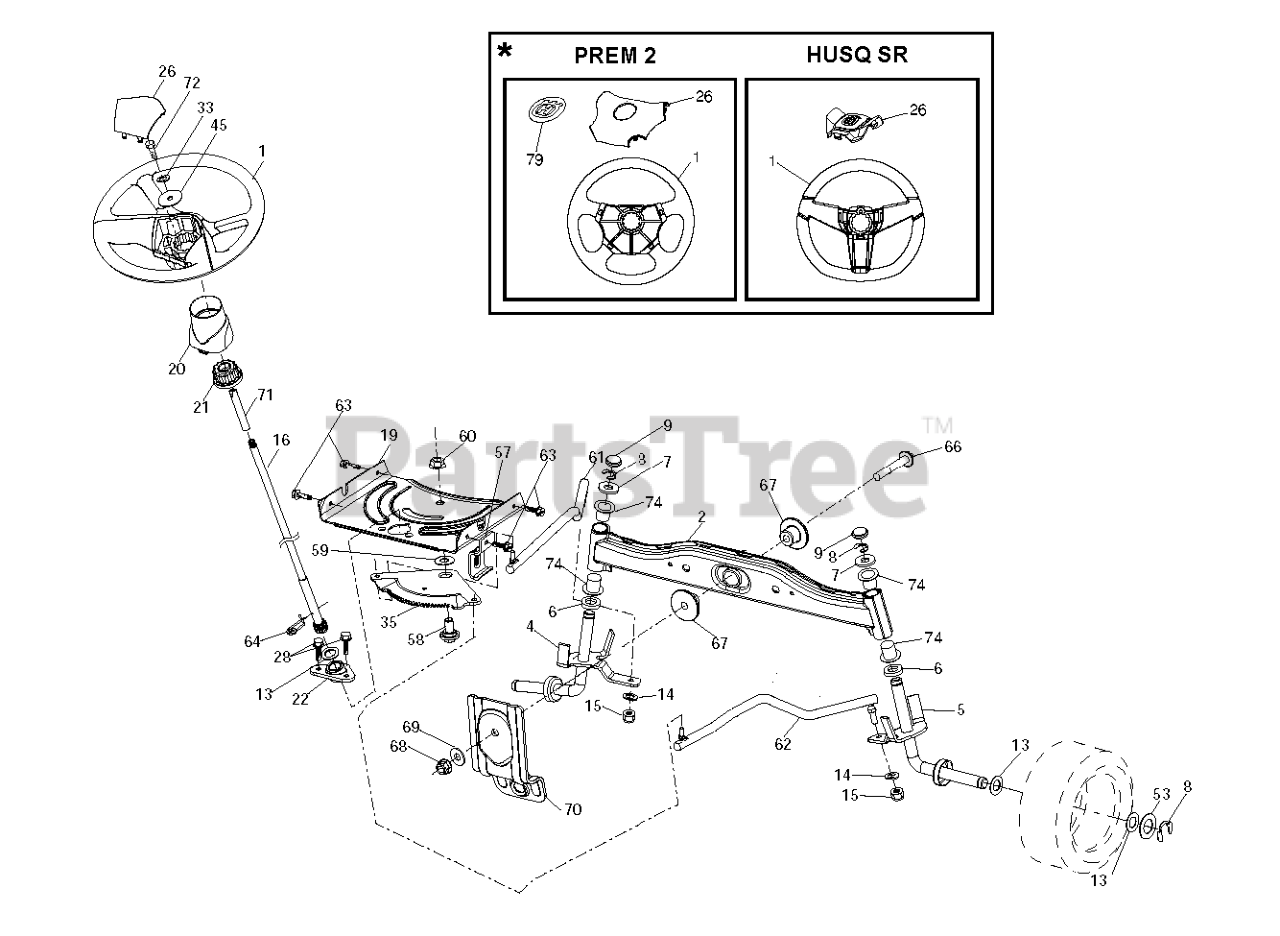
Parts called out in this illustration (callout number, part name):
1	STEERING WHEEL
1	RP WHEEL.STEER.HUSQ.PREM.OVMLD
2	AXLE HALF ASM-WELDED
4	SPINDLE.STEERING.ASM.LH.13".TI
5	SPINDLE.STEERING.ASM.RH.13".TI
6	THRUST WASHER
9	CAP.SPINDLE.BLACK
14	WASHER, LOCK 3/8
15	NUT CROWNLOCK 3/8-24
16	SHAFT STEERING
19	PLATE.STEER.DDL.NLT/NG
20	BOOT, STEERING
21	ADAPTER, WHEEL STNG..
22	BUSHING.ASM.STEERING.A
26	RP INSERT.CAP.WHL.STRG.HUSQ.
28	SCREW, 3/8-16X3/4
33	WASHER.LOCK.HVY.HLCL.SPR.5/16
35	GEAR.SECTOR.PLATE.DDL.
45	WASHER.11/32
53	WASHER.HARDENED
57	BRACKET.UPSTOP.TEX
58	BOLT.SHOULDER.SECTOR.P
59	WASHER.THURST.SECTOR.S
60	NUT FLANGE LOCK 5/8-11
61	DRAGLINK.LH.BALLSTUD.D
62	DRAGLINK.RH.BALLSTUD.D
63	SCREW
64	RETAINER.CLIP.SPRING.S
66	BOLT HEX FGHD 7/16-14 X 3 SERR
67	BUSHING.PM.FRONT AXLE
68	NUT.LOCK.FLANGE.7/16
69	WASHER.1.5X.505X.118
70	BRACKET.SUSP.MWR.FRT.30"SRD
71	SHAFT EXTENSION STEERING
72	BOLT YT
74	BRNG T
